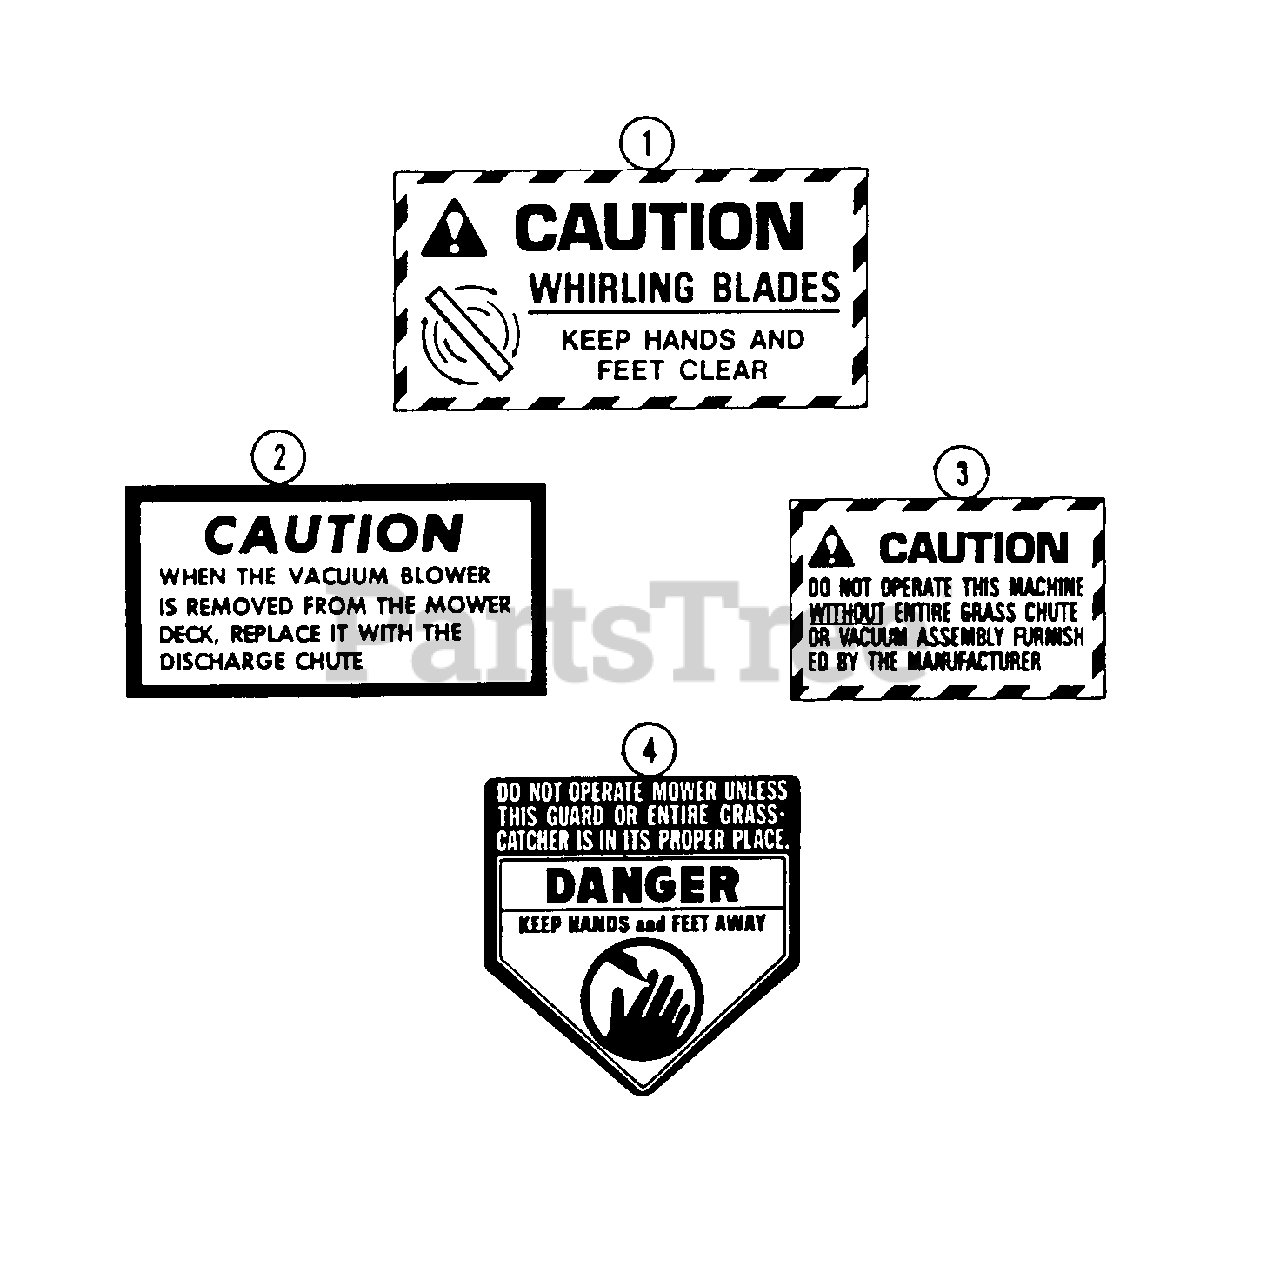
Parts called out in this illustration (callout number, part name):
1	DECAL - "Whirling Blades"
2	DECAL - "Caution" discharge chute
3	DECAL - "Caution" grass chute
4	DECAL - "Danger"
